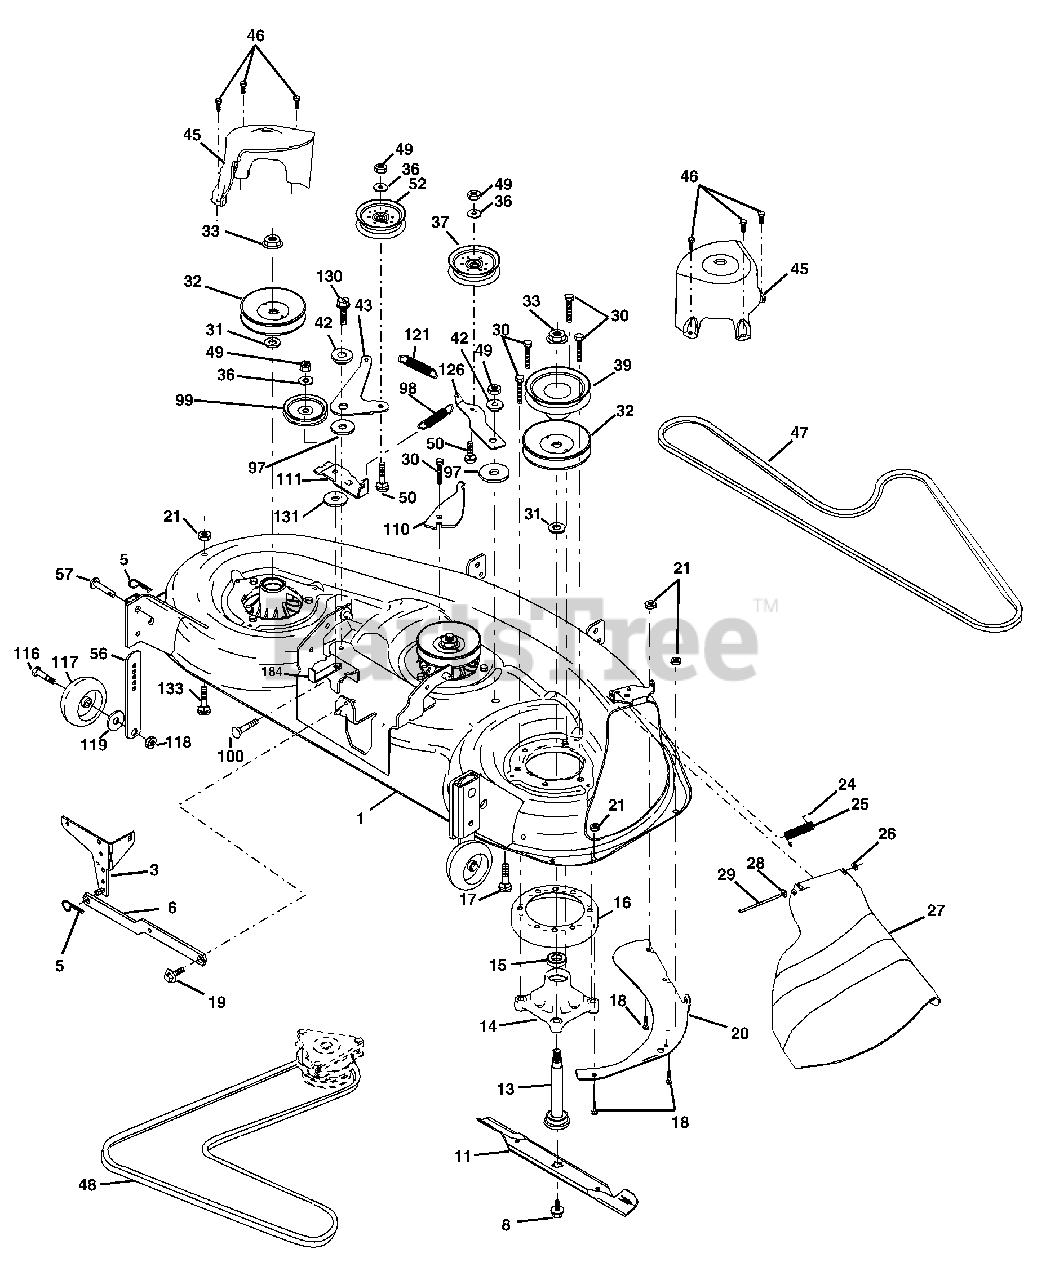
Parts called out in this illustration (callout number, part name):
1	Deck Weldment Mower 48
3	Bracket Asm., Sway Bar
5	Retainer Spring
6	Bar Sway Deck
8	Bolt, 7/16 Asm. Blade
11	Blade, 48 Mulching
11	Blade Hi Lift
13	Shaft Asm.
14	Housing Mandrel 48"
15	Bearing, Ball, Mandrel
16	Stripper, Mower
17	Bolt Rdhd Sq Neck 3/8-16 x 1.25
18	Bolt, Carriage 5/16-18 x 5/8
19	Bolt, Hex Hd. Shoulder 5/16-18
20	Baffle, Vortex Mower
21	Nut, Crownlock 5/16-18 UNC
24	Cap, Sleeve
25	Spring, Torsion
26	Nut, Push
27	Shield, Deflector Mower
28	Washer 11/32 x 5/8 x 16 Ga.
29	Rod, Hinge
30	Screw, Thdroll, Washer Head
31	Washer, Spacer Mower Vented
32	Pulley, Mandrel
33	Nut, Flg. Top Lock Cntr. 9/16
36	Washer 13/32 x 13/16 x 16 Ga.
37	Pulley, Idler, Flat
39	Pulley, Idler, Driven
42	Spacer, Retainer
43	Arm, Idler Secondary
45	Cover, Mandrel Deck
46	Screw, Thdroll. 1/4-20 x 5/8
47	V-Belt, Mower, Secondary
48	V-Belt, Mower, Primary
49	Nut, Crownlock 3/8-16 UNC
50	Bolt, Carr. 3/8-16 x 1-1/2 Gr. 5
52	Pulley Idler Flat 46 Pri. Drive
56	Bar Pnt Adjusting Wheel Gauge
57	Pin Head Rivet
74	Nut Crownlock 3/8-16
97	Washer Hardened
98	Spring Primary Drive
99	Pulley Idler "V"
100	Bolt RDHD Sqnk 3/8-16 Unc x 2
110	Arm Spring Secondary
111	Arm Spring Tension
116	Bolt, Shoulder
117	Gauge Wheel
118	Nut, Centerlock 3/8-16 UNC
119	Washer 3/8 x 7/8 x 14 Ga.
121	Spring Secondary Drive
126	Arm, Idler, Primary Deck
130	Screw 3/8-16 x 1
131	Washer 13/32 x 1 x 6 Ga.
133	Bolt 5/16-18 x 3/4
184	Keeper Belt Idler
191	Bolt Fin Hex 3/8-16unc x 3/4 Gr. 5
